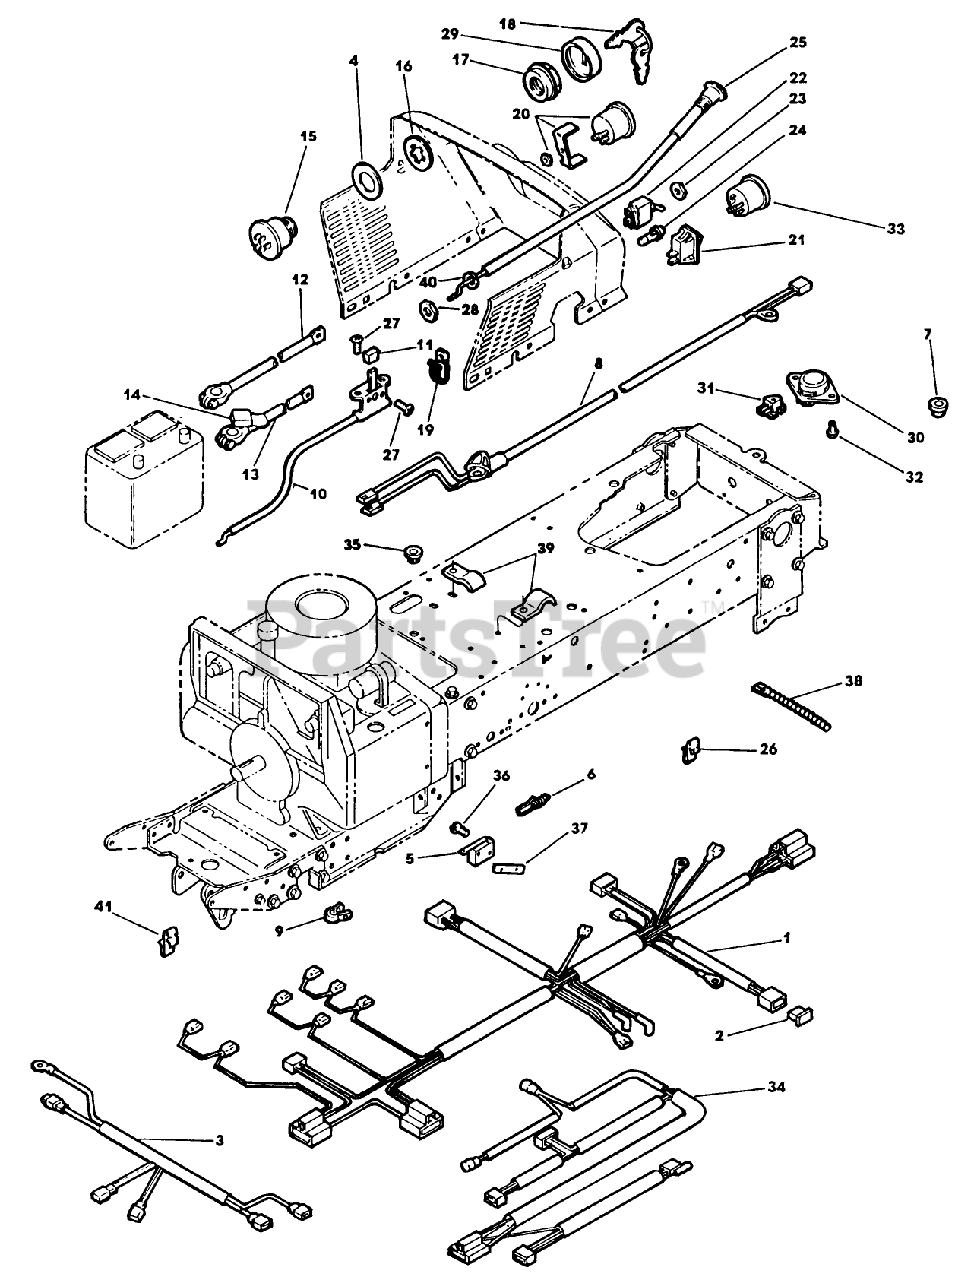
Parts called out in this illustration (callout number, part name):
4	WASHER
10	CONTROL - THROTTLE
11	THROTTLE KNOB
17	NUT
18	KEY
21	SWITCH ASSEMBLY
22	SWITCH-PTO W/SAFTY
24	LIGHT-PTO INDICTOR
25	CONTROL - CHOKE
26	CLIP-RETAINER, WIRE
28	NUT-HEX
29	BEZEL
30	SWITCH,SEAT
31	SWITCH
40	WASHER
41	CLIP
